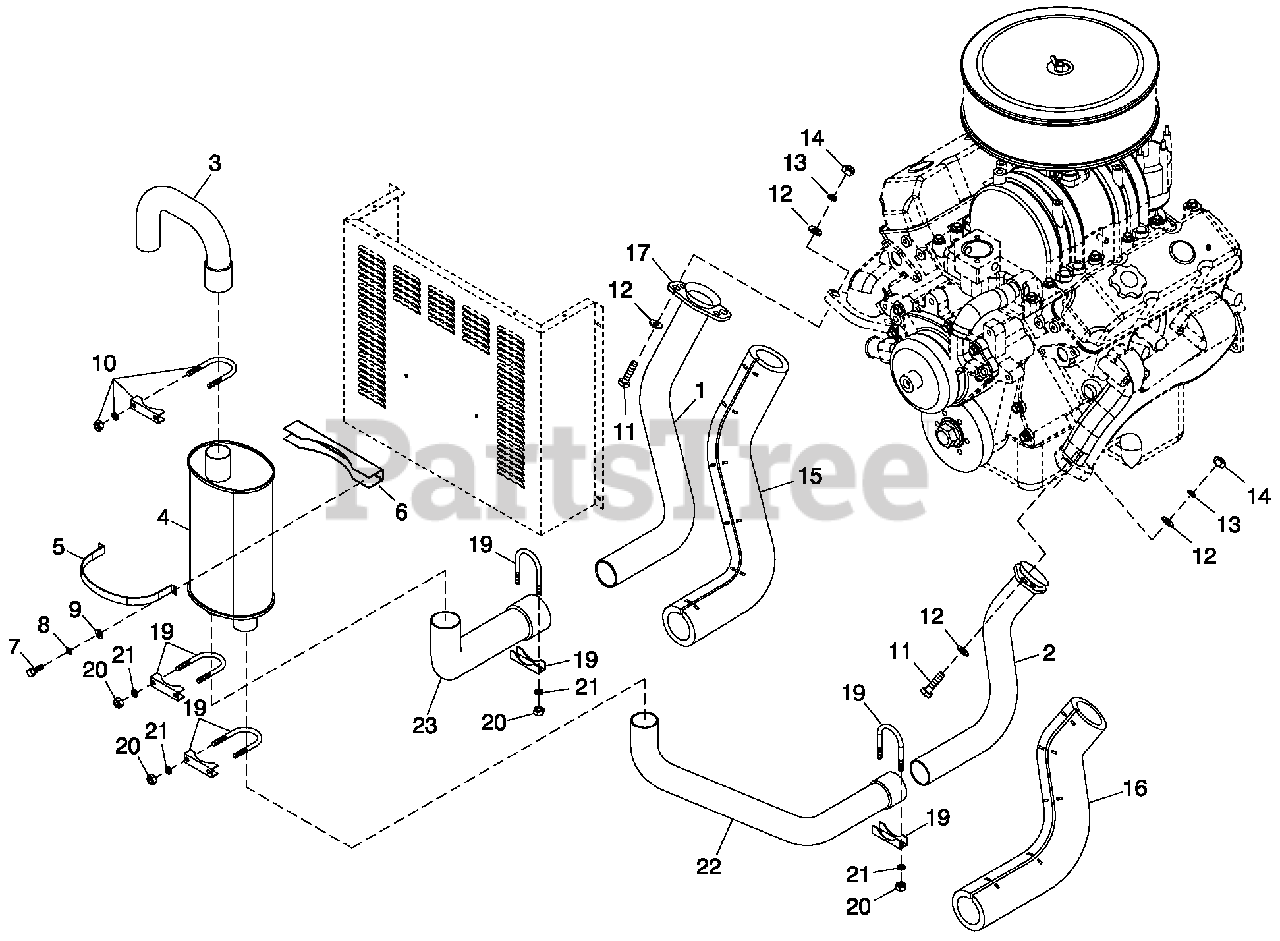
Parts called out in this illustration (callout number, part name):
1	PIPE R/H SIDE MUFFLER
2	PIPE L/H SIDE 3.9L CPL
3	PIPE EXHAUST MUFFLER OUT
4	MUFFLER 7" X 9"-(2) 2" IN/2.5" OUT
5	MUFFLER STRAP
6	MUFFLER BRACKET STIFFENER
7	SCREW HHC M6-1.0 X 16 G8.8
8	WASHER LOCK M6-1/4
9	WASHER FLAT 1/4-M6 ZINC
10	BOLT U 3/8-16 X 2.62
11	SCREW HHC M12-1.75 X 75 SS
12	WASHER FLAT 1/2 SS
13	WASHER LOCK 1/2 SS
14	NUT HEX M12-1.75 G8 SS
15	EXHAUST BLANKET 549MM LONG (R/H)
16	EXHAUST BLANKET 448MM LONG (L/H)
17	EXHAUST FLANGE 2" PIPE
19	BOLT U 5/16-18 X 2.25
20	NUT HEX 5/16-24 STEEL
21	WASHER LOCK M8-5/16
22	PIPE L/H SIDE MUFFLER
23	PIPE R/H SIDE 3.9L CPL
